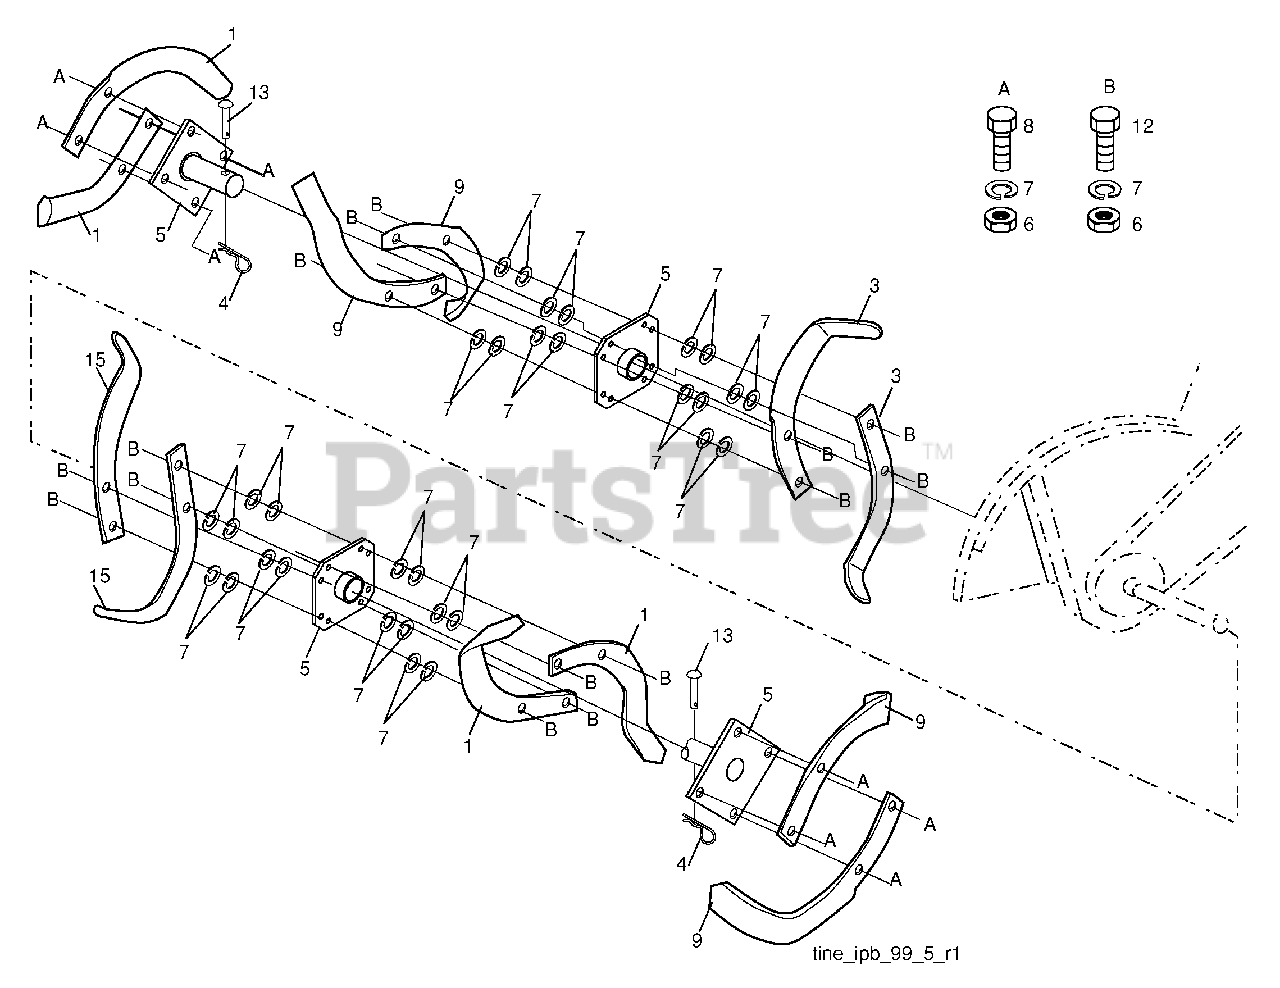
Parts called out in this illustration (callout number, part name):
1	Tine, Outer, L.H.
3	Tine, Inner, L.H.
4	Retainer, Spring Zinc
5	Assembly, Hub and Plate
6	Nut, Hex 3/8-24
7	Washer, Lock 3/8
8	Bolt, Hex 3/8-24 x 1
9	Tine, Outer, R.H.
12	Bolt H 3/8-24 x 1-1/2
13	Clevis Pin
